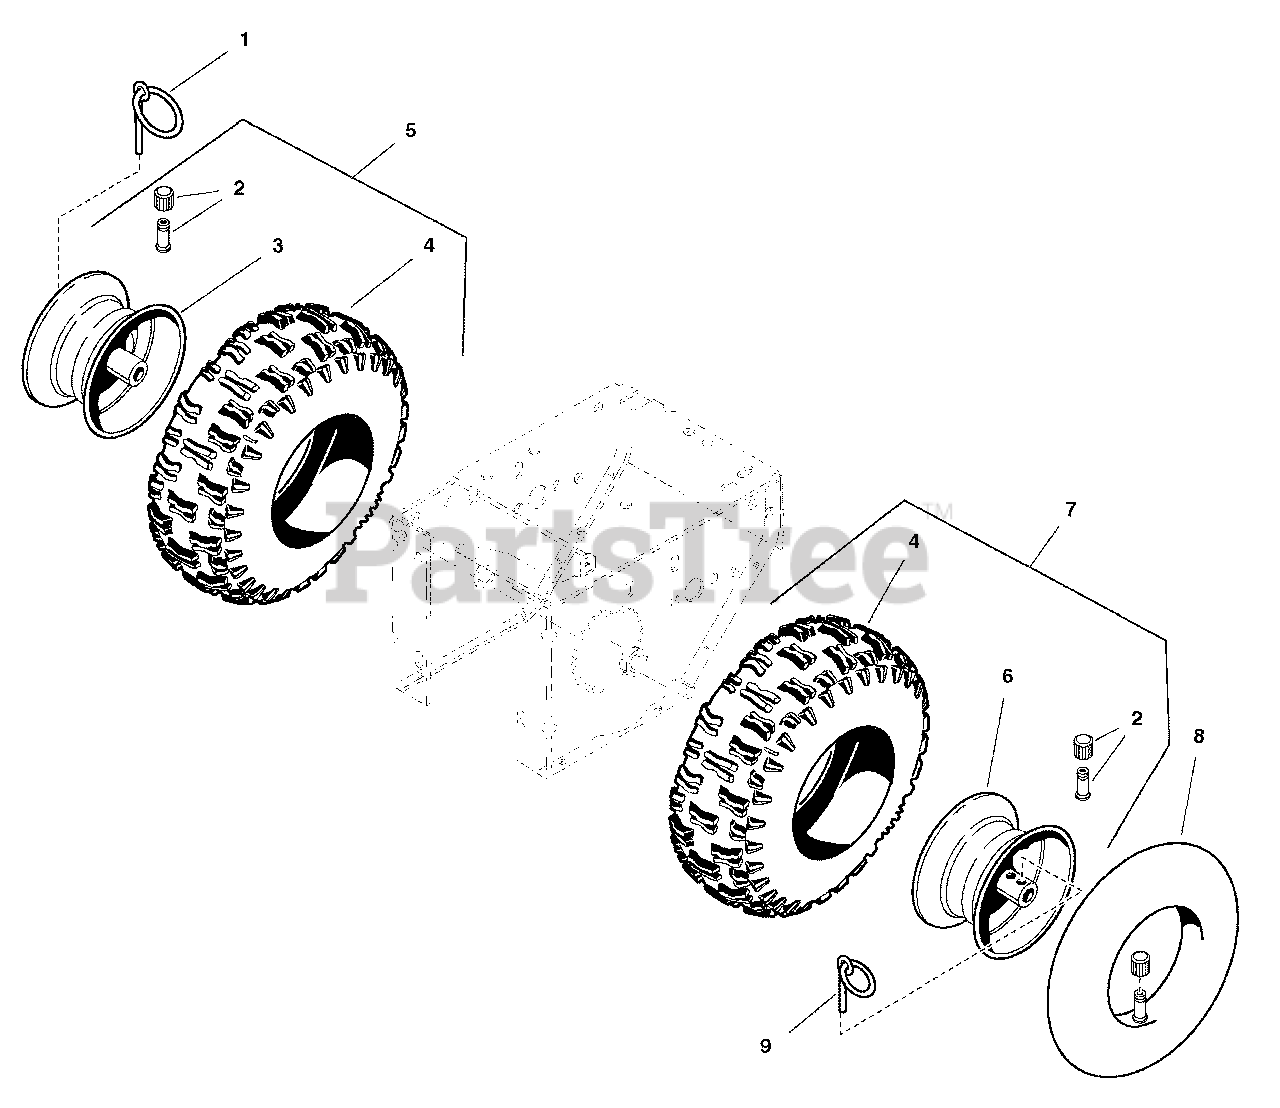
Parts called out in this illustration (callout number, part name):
1	PIN, Klik
2	VALVE Stem & Cap
3	HUB, Wheel R.H., 3-3/4 Wide 8 Diameter 3/4 ID
3	HUB, Wheel, RH
4	TIRE, 4.80-4.00-8
4	TIRE, 16 x 6.50-6
5	WHEEL & TIRE ASSEMBLY, RH (Includes Ref. Nos. 3, 4 & 5)
6	HUB, Wheel, LH
7	WHEEL & TIRE ASSEMBLY, LH (Includes Ref. Nos. 3, 5 & 7)
